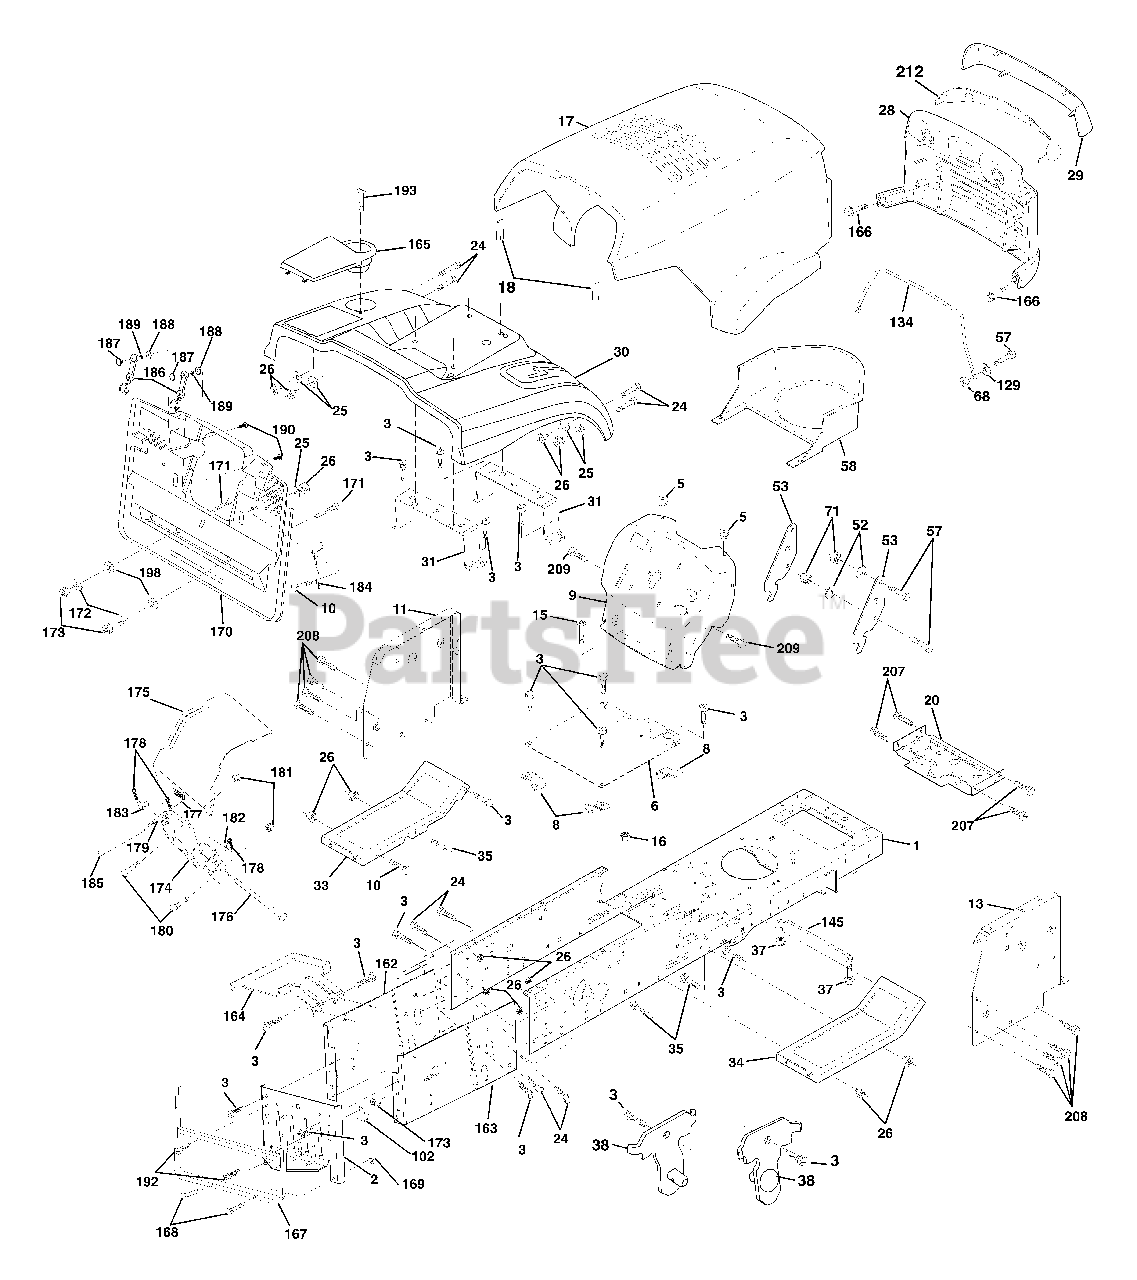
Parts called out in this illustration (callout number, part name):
1	Chassis Stamping
3	Screw 3/8-16 x 3/4
5	Bumper Hood/Dash
8	Clip Insulator 13/32 Mtg. Hole
10	Bolt, Carriage 3/8-16 x 3/4
11	Panel, Dash, L.H.
13	Panel, Asm. Dash R.H.
14	Screw Thdrol 3/8-16 x 1/2
15	Screw, Machine, Truss Head 5/16-18 UNC x 3/4
16	Nut
17	Hood Assembly
18	Bumper Hood
20	Plate Mtg. Battery/Fuel Tank
25	Washer 13/32 x 13/16 x 12 Gauge
26	Nut
28	Grille PL
29	Lens, Grille
31	Bracket, Fender Support
33	Footrest, L.H.
34	Footrest, R.H.
37	Screw Thdrol 5/16-18 x 1/2 TYT
38	Bracket Asm Pivot Mower Rear
52	Washer 9/32 x 7/8 x 16 Ga.
53	Bracket Pick off LT/Pl Husq
57	Bolt, Fin Hex 1/4-20 UNC x .75
58	Duct Air Engine Pl/Lt
68	Nut Keps Hex 1/4-20 Unc
71	Nut Crownlock 1/4-20 Unc
102	Clip Line Fuel 13-13/32 Mtg. Hole
129	Washer 9/32 x 5/8 x 16 Ga.
134	Rod Support Hood Husq P/L
145	Rod Pivot Chassis/Hood
162	Bracket Exten Chassis Lh CRD
163	Bracket Exten Chassis Rh CRD
164	Support Battery CRD
165	Cover Battery CRD Lt
166	Screw Hwhd Hi-Lo #13-16 x 3/4
167	Support Asm. Backplate WLDMNT
168	Bolt, RDHD SHT NK 1/4-20 x 1-1/2
169	Nut, Lock 1/4 LGE FLG Gr. 5 Zinc
170	Cover, Backplate Plastic Black
171	Bolt Rdhd Sqnk 3/8-16 x 2-1/2 Gr. 5
172	Washer 13/32 x 1-1/4 x 16 Ga.
173	Nut, Keps Hex 3/8-16 UNC
174	Bracket Switch FBI CRD
175	Guard Door Rear CRD
176	Pin Hinge Pivot
177	Spring Bagger Top LH Black
178	Pin Cotter 3/32 x 3/4 Cad Zinc
179	Rod Pivot FBI CRD
180	Bolt Hex HD 5/16-18 UNC x 1
181	Nut Crownlock 5/16-18
182	Washer .385 x .625 x 11 Ga.
183	Washer 13/32 x 13/16 x 16 Ga.
184	Bracket Actuator Bagger CRD
185	Tube Lever Switch FBI CRD
186	Latch Asm Mulch/Bagger
187	Nut Weld
188	Washer #10
189	Washer Lock #10
190	Washer Truss Head Phil 10-24 x 5/8
192	Screw Thdrol 3/8-16 x 1-1/4
193	Screw Truss 1/4-20 x 3/4
194	Screw 3/8-16 x .75
207	Screw Thdrol 5/16-18 x 1/2
208	Screw Thdrol 3/8-16 x 1/2
209	Screw Hex Washer Thdr. 3/8-16 x 3/4
212	Insert Lens Reflective
